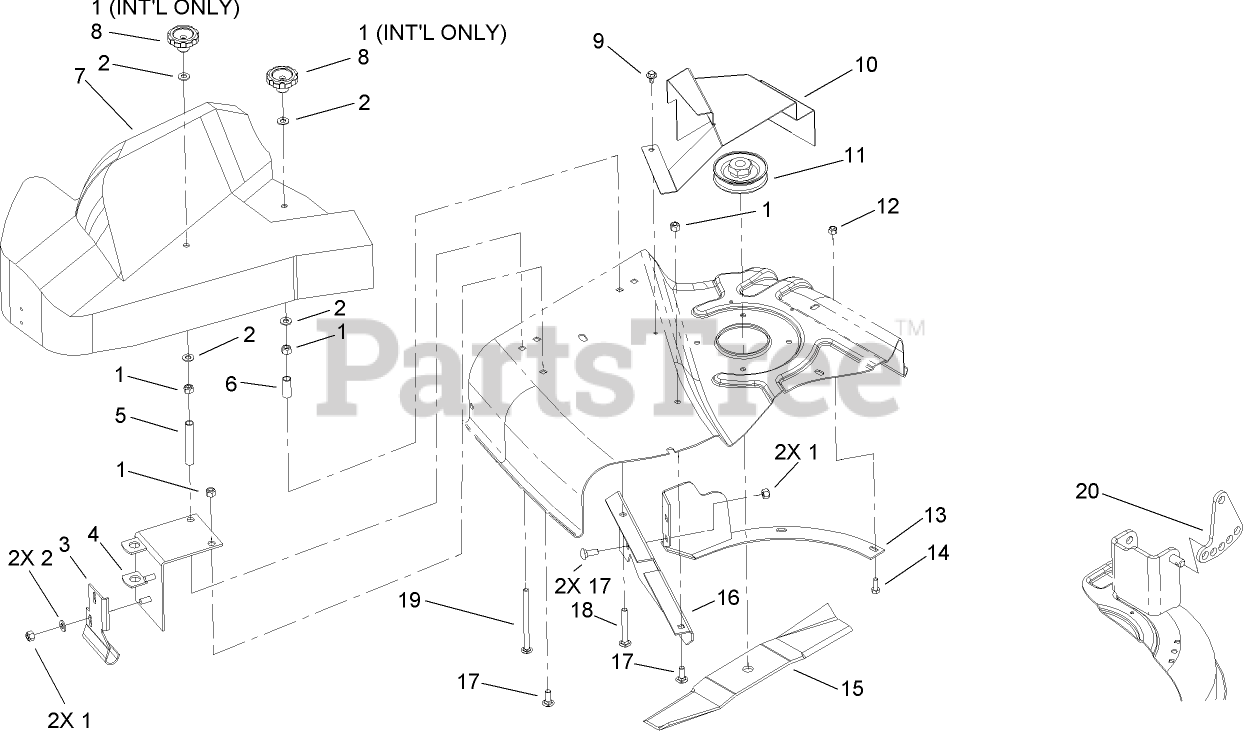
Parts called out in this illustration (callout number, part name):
1	NUT-LOCK, NI
2	WASHER-PLAIN
3	BRACKET-PIVOT
4	PIVOT-BRACKET
5	TUBE-SPACER
6	TUBE-LATCH
7	BELT SHIELD ASM
9	SCREW-HHFTF
10	BELT COVER ASM
11	PULLEY
12	NUT-LOCK, NI
13	RING-BAGGING, RH
14	SCREW-HH
15	BLADE-LIFT, HIGH
16	BAFFLE-REAR
17	SCREW-CARR
18	SCREW-CARR
19	SCREW-CARR
20	LINK-HOC, ADJUSTING
